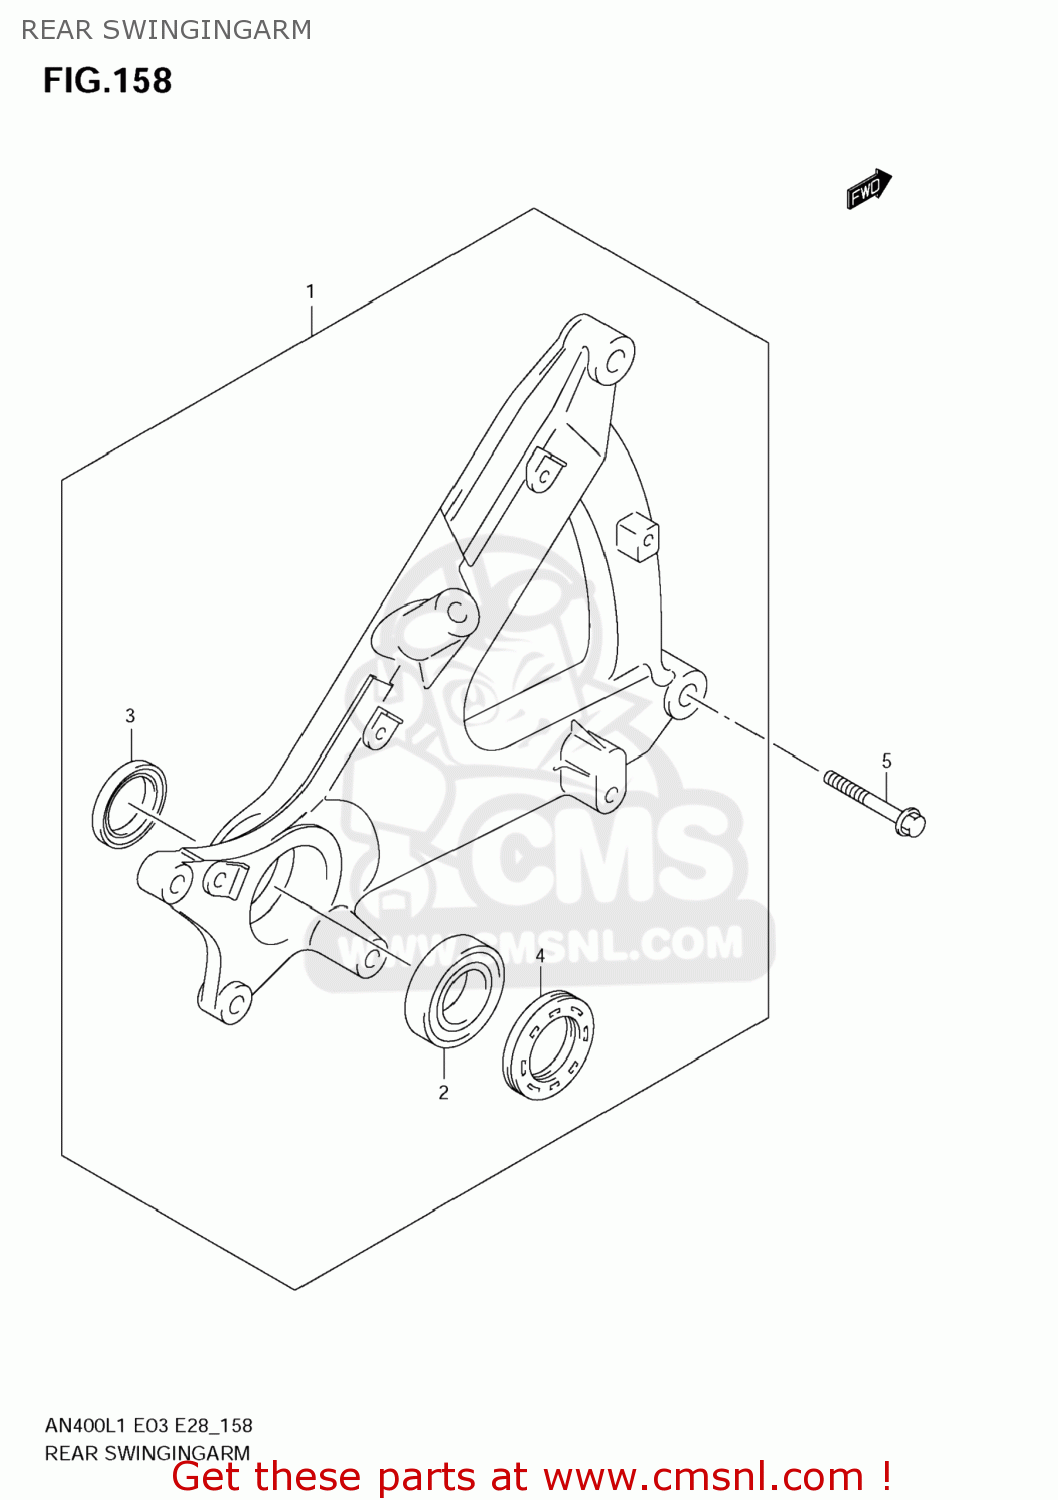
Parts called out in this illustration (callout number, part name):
1	SWINGINGARM ASSY,RR
2	BEARING(25X52X15)
3	SEAL,OIL(32X47X7)
4	SEAL,OIL(32X52X7)
5	BOLT
